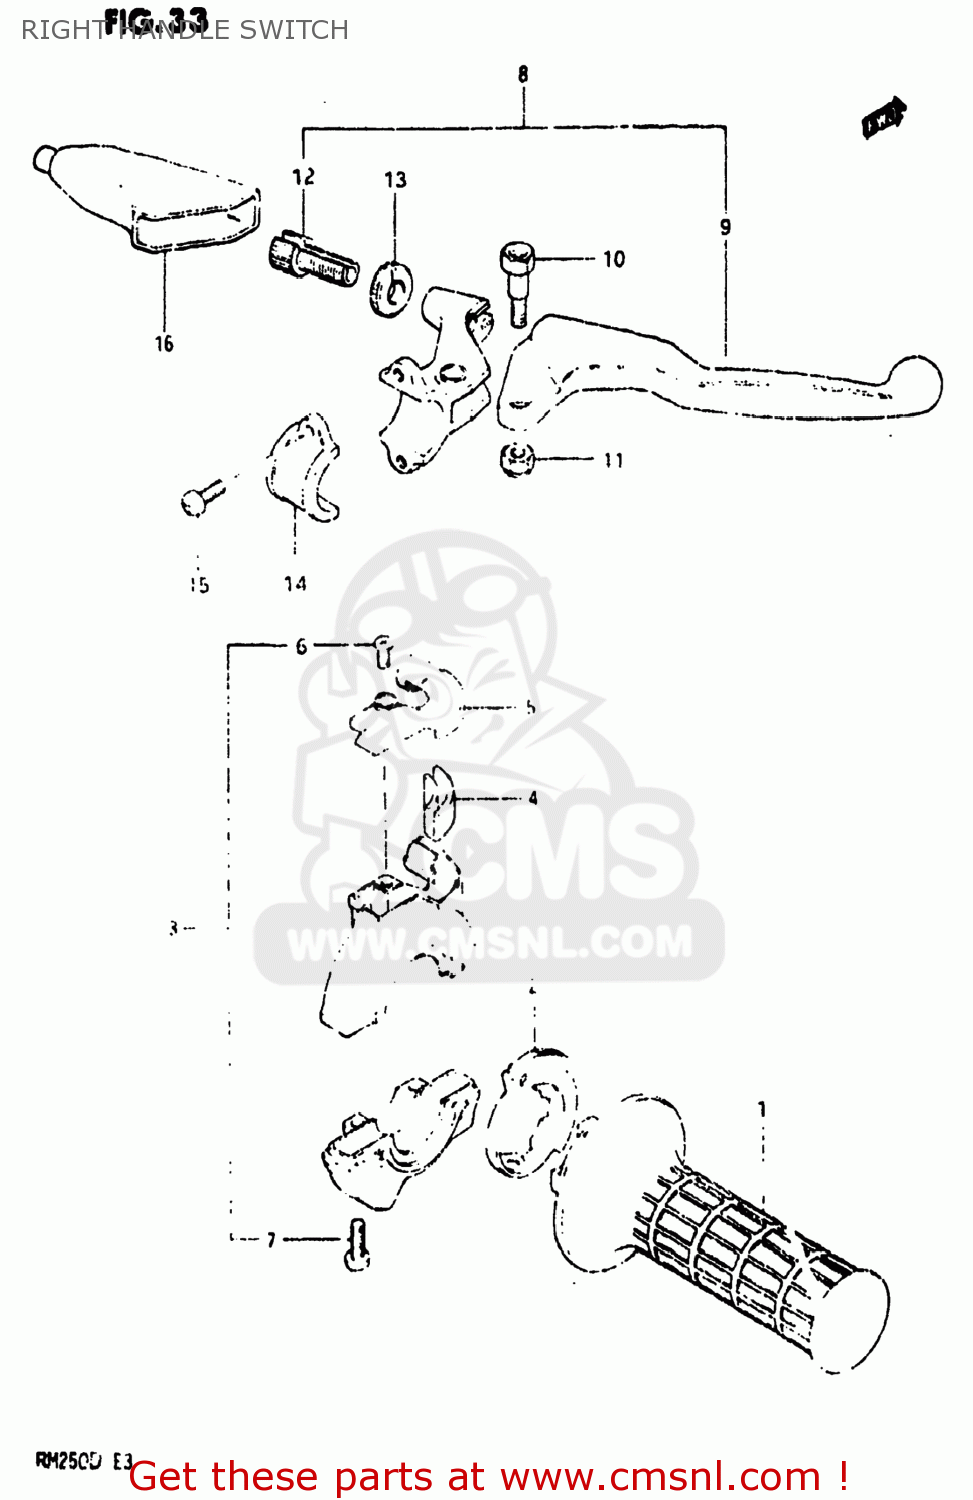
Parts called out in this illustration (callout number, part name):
1	GRIP,THROTTLE
2	ROTOR,THROTTLE GRIP
3	CASE ASSEMBLY,THROTTLE
4	GUIDE PIECE,THROTTLE
5	COVER,THROTTLE CASE
6	SCREW
7	SCREW
8	LEVER ASSEMBLY,BRAKE
9	LEVER,BRAKE
10	BOLT,LEVER
11	NUT 6MM
12	ADJUSTER,CABLE
13	NUT,CABLE ADJUSTER
14	BRACKET,CLUTCH LEVER HOLDER
15	SCREW
16	COVER,CLUTCH LEVER
